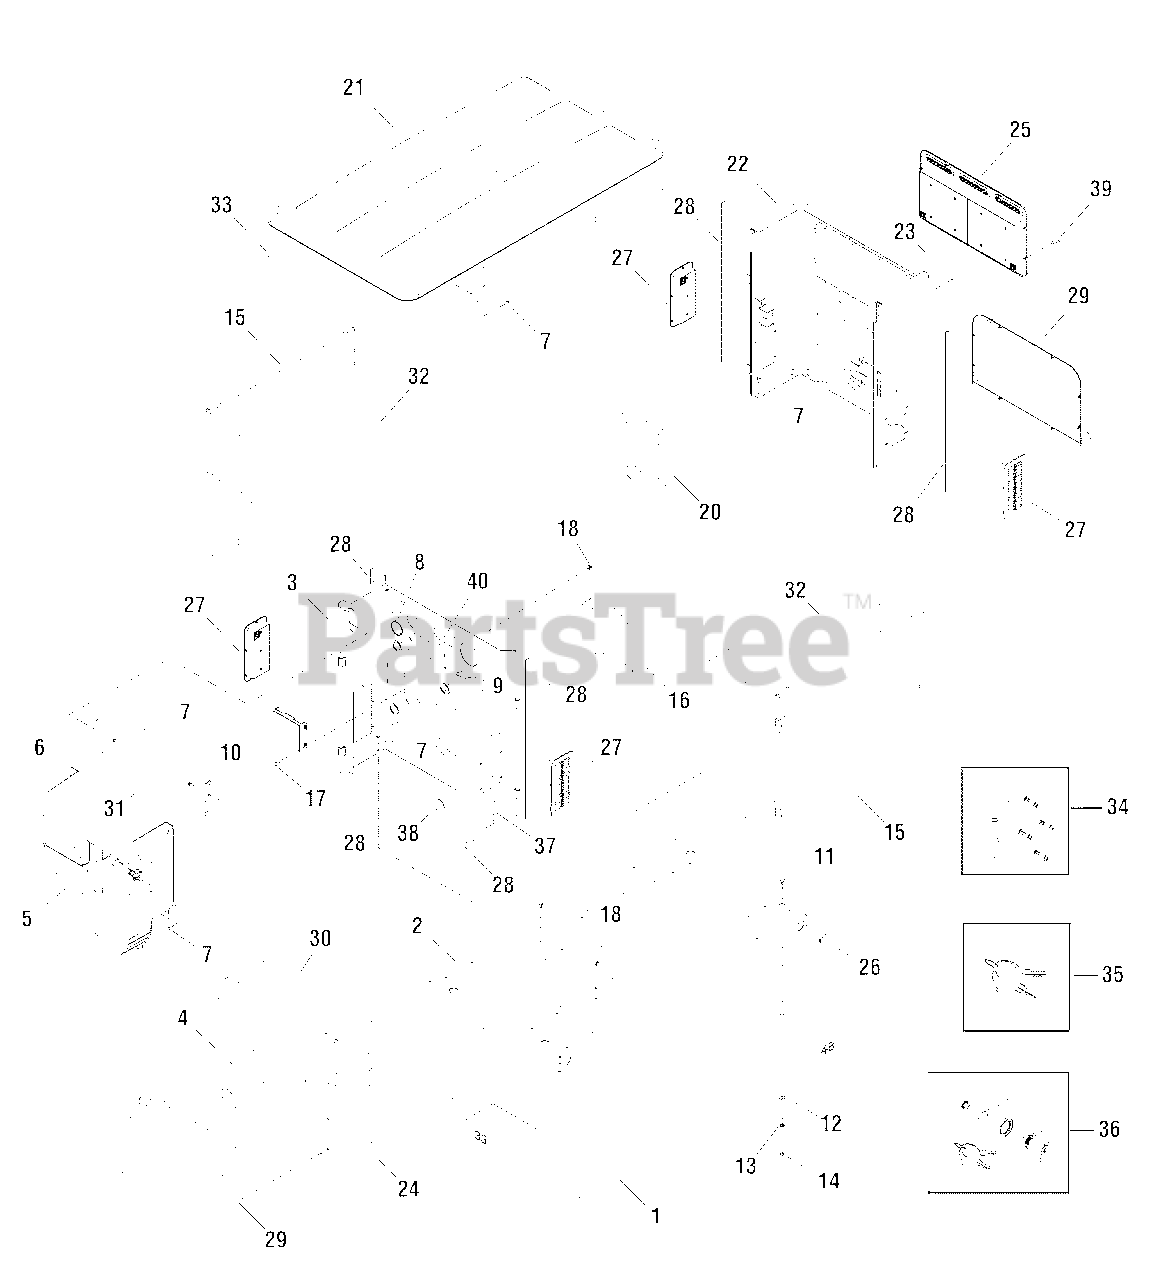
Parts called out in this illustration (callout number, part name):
3	BULKHEAD, Engine
7	BOLT
10	REGULATOR, Voltage
11	* CAPSCREW, Hex Head, 3/8-16 x 1
12	* WASHER, Flat, 3/8 - M10
13	* WASHER, Lock, 3/8
14	* NUT, 3/8-16
16	SEAL, Foam
20	SEAL, Foam
22	BULKHEAD, Alternator
29	COVER, Air Intake
37	DECAL
39	SCREW
